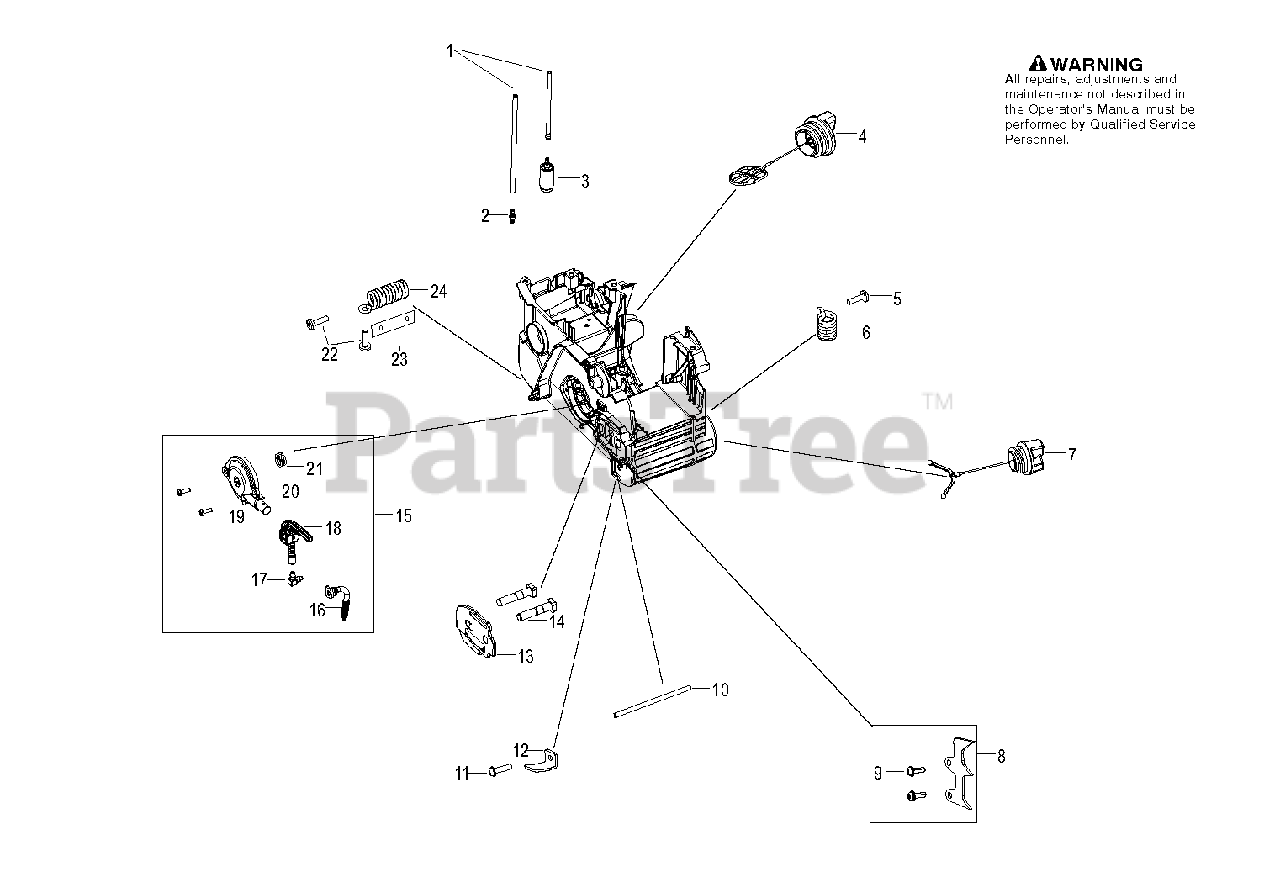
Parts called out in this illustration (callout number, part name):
1	KIT-LINE(FUEL)
2	FUEL LINE FITTING
3	FUEL PICK-UP ASSY
4	TANK CAP
6	FRONT SPRING ASSY
7	OIL TANK CAP
8	SPIKE 36/41
10	OIL VENT ASSY
11	SCREW M5.38-14X22.225MM
12	CHAIN CATCHER 36/41
13	BAR PLATE
15	OIL PUMP KIT
16	OIL PICK UP W/FILTER ASSY
18	OIL BLOCK
19	SCREW 6-19X.437
20	OIL PUMP ASSY
21	WORM GEAR
23	4V STRAP
